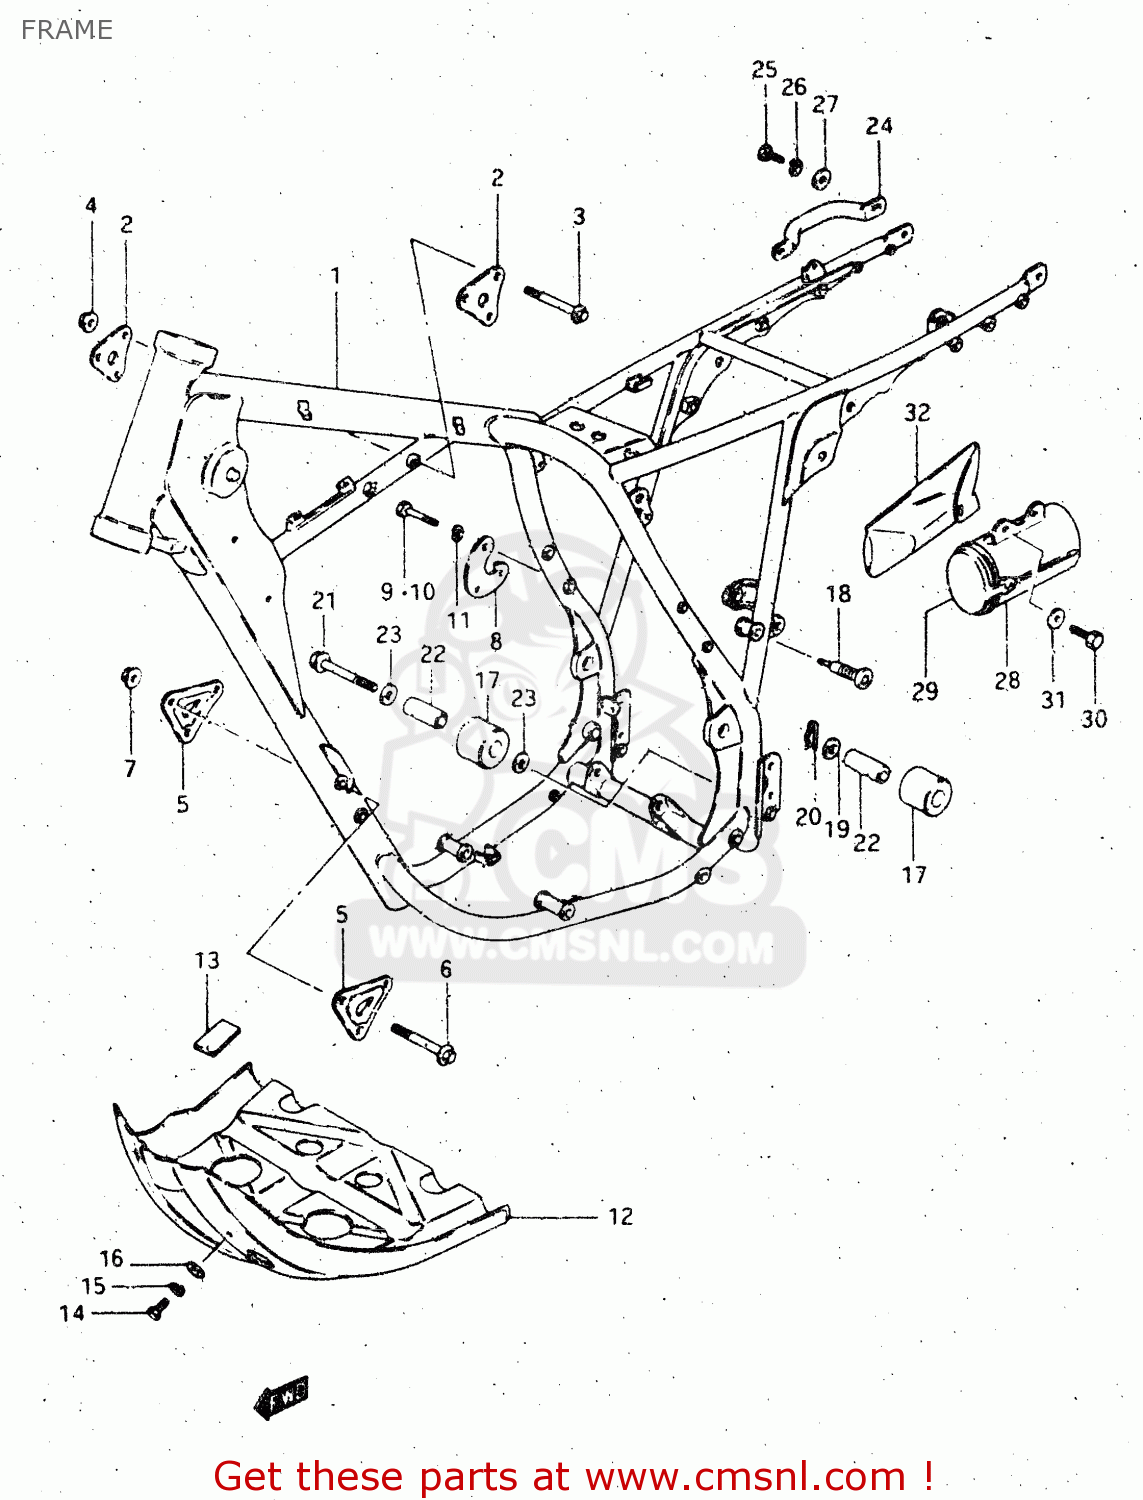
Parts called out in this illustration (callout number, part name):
1	FRAME (BLUE)
2	PLATE,ENGINE MOUNTING,UPPER
3	BOLT
4	NUT
5	PLATE,ENGINE MOUNTING,FRONT
6	BOLT 8X67
7	NUT
8	PLATE,ENGINE MOUNTING
9	BOLT, LOWER
10	BOLT
11	LOCK WASHER
12	PLATE,ENGINE,UNDER
13	CUSHION,ENGINE,UNDER
14	BOLT
15	LOCK WASHER
16	WASHER
17	ROLLER,CHAIN LENGTH CONTROL
18	BOLT,CHAIN LENGTH ROLLER
19	WASHER
20	E RING 8MM
21	BOLT(8X45)
22	SPACER,CHAIN LENGTH ROLLER
23	WASHER
24	GRIP,FRAME HANDLE
25	BOLT
26	WASHER,LOCK,8.
27	WASHER
28	HOLDER,TOOL
29	CAP,HOLDER
30	BOLT, UPPER
31	WASHER (6.5X18X1.6)
32	TOOL SET
